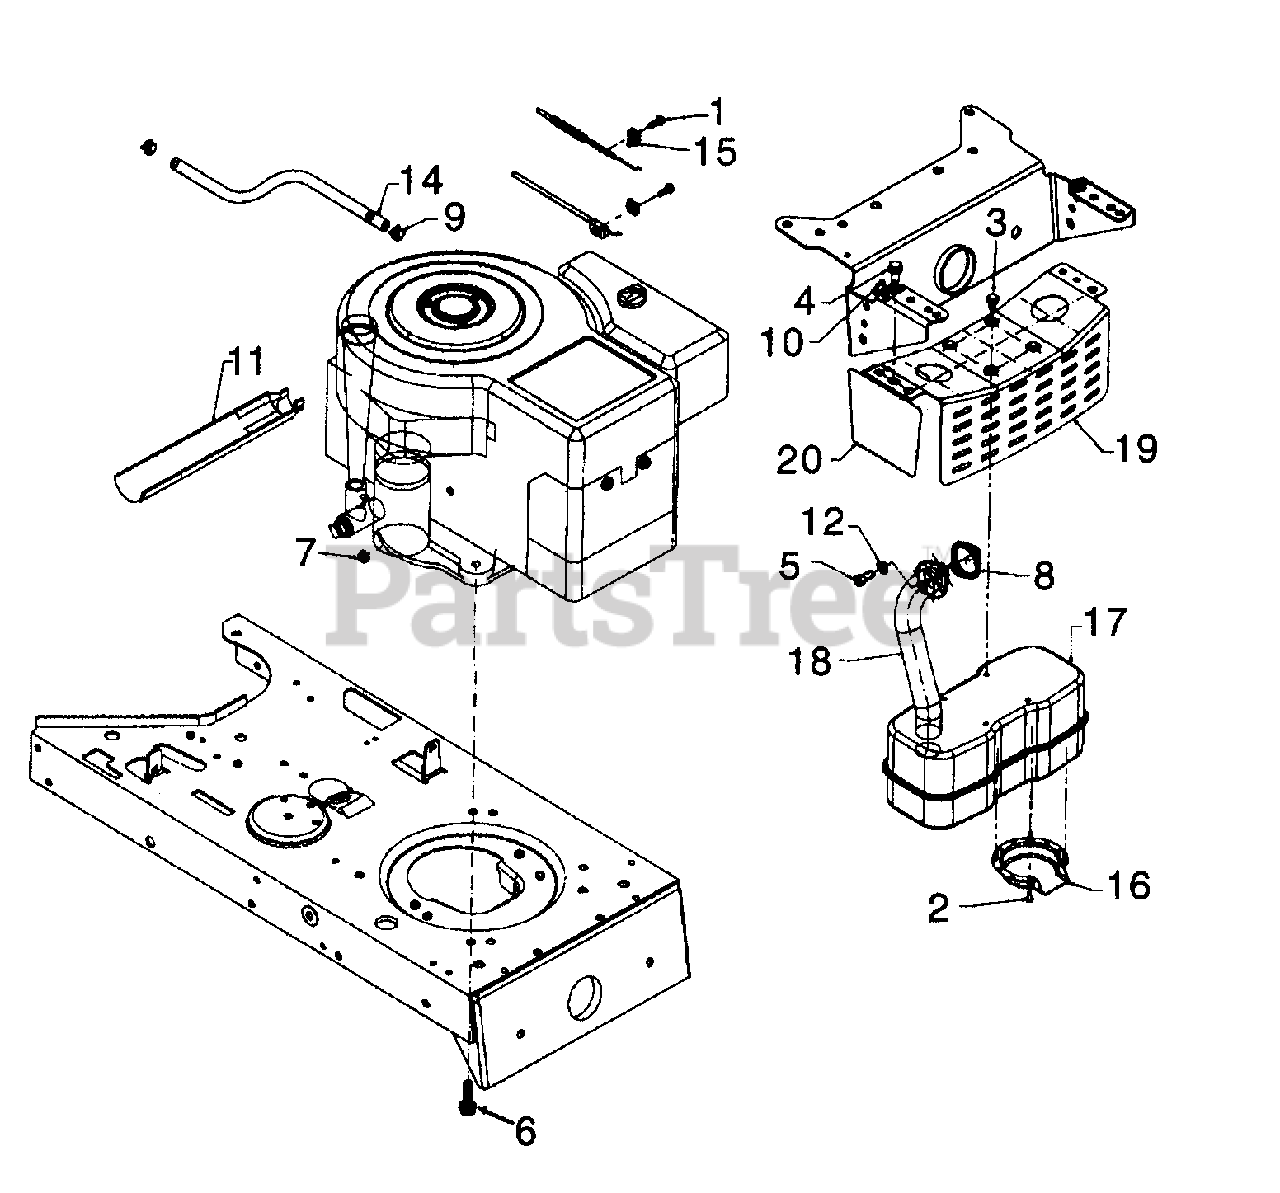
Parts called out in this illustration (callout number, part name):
1	Hex Wash. Scr. #10-32 x .62"
2	Hex Tap Scr. #8-32 x .38" Lg.
3	Hex TT-Tap Scr. 1/4-20 x .5" Lg.
4	Hex TT-Tap Scr. 5/16-18 x .62"
5	Socket Head Scr. 5/16-18 x .62"
6	Hex TT-Tap Scr. 3/8-16 x 1.25"
7	Hex Sems Scr. 1/4-20 Thd.
8	Gasket
9	Hose Clamp
10	Clamp
11	Oil Drain Sleeve
12	Lock Washer 5/16" I.D.
14	Fuel Line 12" Lg.
15	Casing Clamp
16	Muffler Deflector
17	Muffler
18	Exhaust Pipe
20	Shield Brkt.
